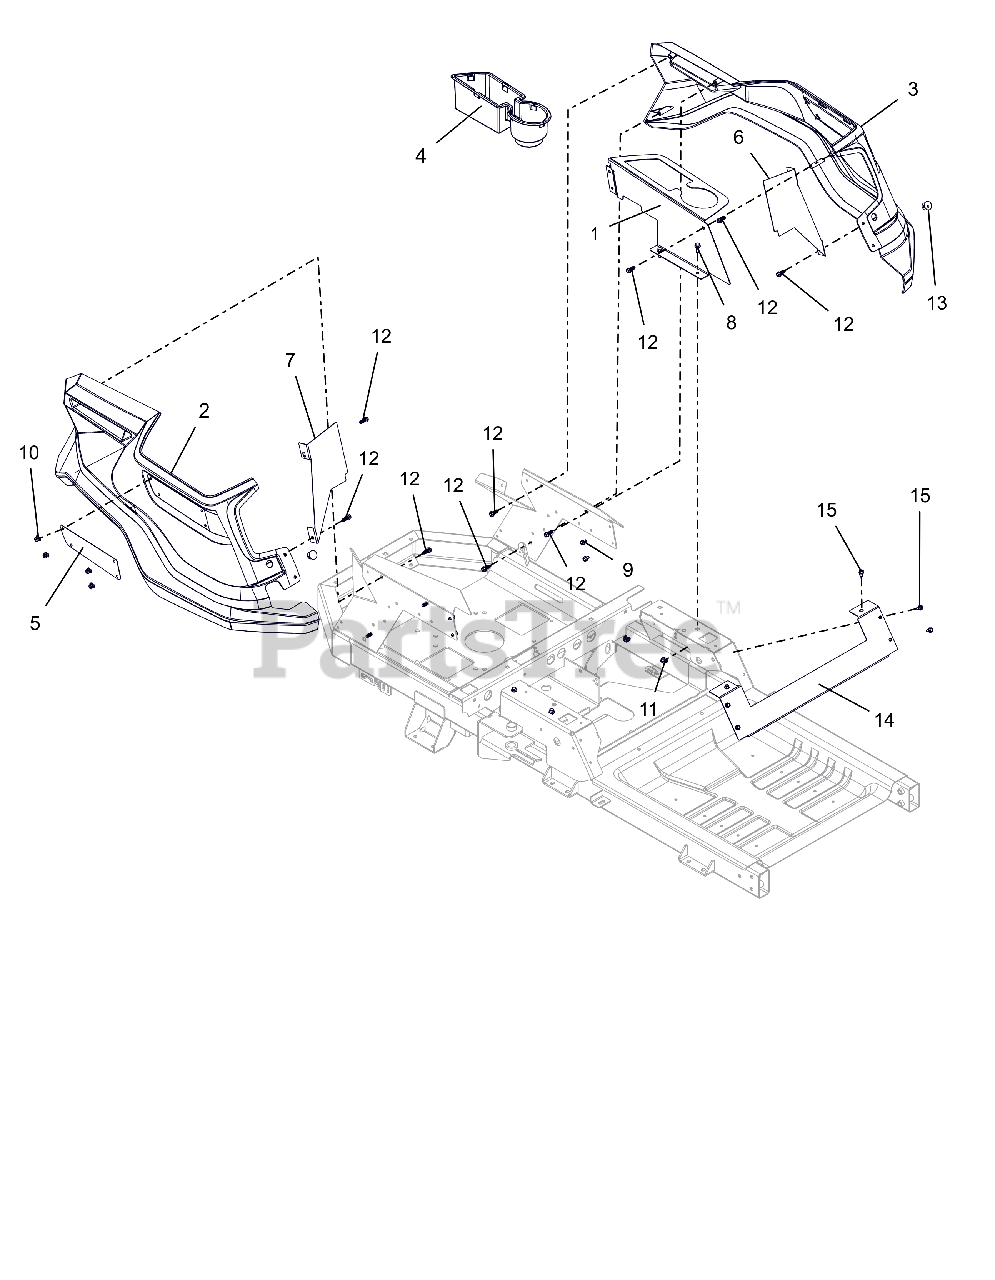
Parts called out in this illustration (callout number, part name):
1	PANEL, LEFT SIDE FENDER MOUNT
2	FENDER, RH IKON
3	FENDER, LH IKON
4	INSERT, CUP/STORAGE HOLDER
5	PLATE, ARIENS NAME
6	PLATE, LH BLOCKER
7	PLATE, RH BLOCKER
8	BLT,HEX-FLG .25-20X.75 G5 BFP
9	SCR,TAP .25-20X.375 HWH TR ZCC
10	RIVET, PLASTIC .195 DIA.
11	NUT RETNR .25-20
12	SCR-.312X.75 #14H H/W/H H/L CZ
13	PLUG, HOLE .75 (BLACK)
14	PLATE, SEAT KICK
15	SCR-TAP .25-20X.50 HWH ZCC
